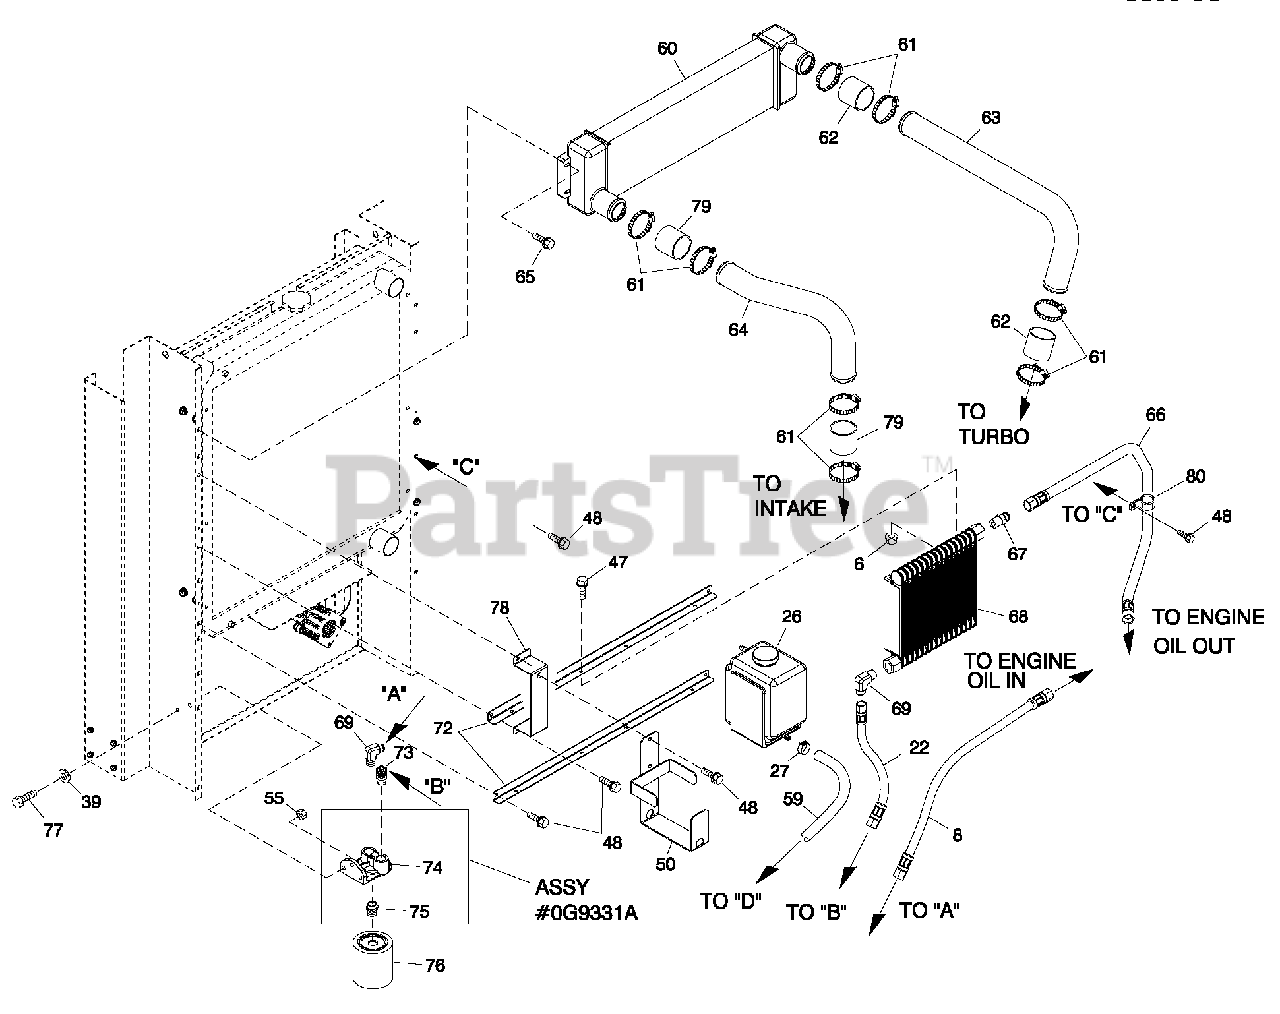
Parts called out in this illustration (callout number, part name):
8	OIL LINE REMOTE FILTER/ENGINE
9	PULLEY FAN V-GROOVE 9"
22	OIL LINE REMOTE COOLER/FILTER
26	TANK COOLANT RECOVERY
27	CLAMP HOSE BAND 1/4
39	WASHER FLAT 5/16-M8 ZINC
47	SCREW HHFC M 6 -1 .0X 2 0 G8.8
48	SCREW THF M6-1 X 16 N W A Z/JS
50	BRACKET COOLANT TANK
55	NUT HEX LOCK M8-1.25 NY INS
59	HOSE 9/32 ID (36" LG)
60	CAC 504W X 152H X 50D 2.4L G2
61	CLAMP CNST TENSION 1.75-2.625
62	HOSE 2 "ID X 3.0"LG
63	TUBE CAC IN G2 TURBO
64	TUBE CAC OUT G2 TURBO
65	SCREW THF M6-1 X 30 N W A DELTA
66	OIL LINE REMOTE ENG/COOLER
69	ADAPTER 90D JIC37 1/2NPT X 3/4
72	MOUNT OIL COOLER 2.4LG 2
73	ADAPTER 45D JIC37 1/2NPT X 3/4
74	MOUNT REMOTE OIL FILTER 2.4 G2
75	NIPPLE-OIL FILTER
76	FILTER 1.5L/2.4LG 2 OIL
77	SCREW HHC M 8 -1 .25 X 25 C 8 .8
78	ASSY PCB LCL SENSOR (USE WITH I/N 16, P/N 0H1827 ONLY)
